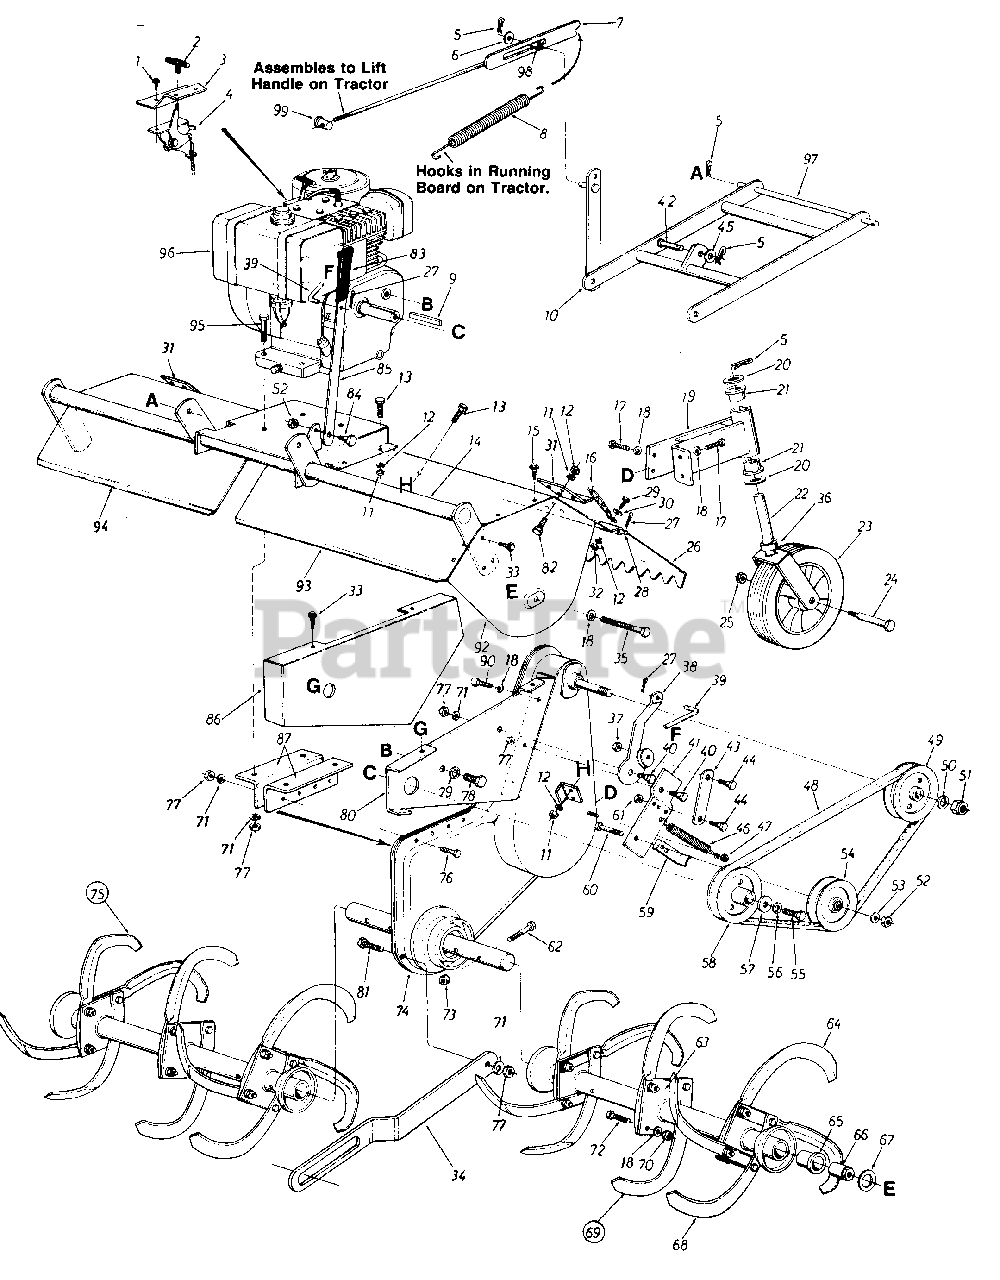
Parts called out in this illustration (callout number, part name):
1	Hex Wash. Hd. Self-Tap Scr. #8 x .50" Lg.
2	Throttle Control Knob-
3	Throttle Control Bracket
4	Throttle Control Ass'y. Comp.
5	Internal Cotter Pin
6	Fl-Wash. 1/2" I.D. x .93" O.D.
9	Sq. Key 1/4" x 1/4" x 2.00" Lg.
12	L-Wash 1/4" I. D.
13	Hex Bolt 1/4-28 x .62" Lg.
16	#2 Dog Chain x 20" Lg.
17	Hex Wash. Hd. Self-Tap Scr. 3/8-24 x .75" Lg.
18	L-Wash. 3/8" I.D.
21	Flange Bearing 3/4" I.D. x 1.00 O.D.
24	Shoulder Bolt .623" I.D. x 3.62" Lg.
25	Hex Cent. L-Nut 7/16-14 Thd.
28	L.H. Flap Rod
29	Hex Bolt 1/4-20 x .62" Lg.
30	Fl-Wash. 1/4" I.D.
33	Hex Wash. Hd. Self-Tap Scr. 1/4" x.62" Lg.
36	Spacer .752" I.D. x 1.25" O.D.
37	Hex Cent. L-Nut 5/16-18 Thd.
40	Shoulder Bolt 7/16" Dia. x 1.75" Lg.
45	Fl-Wash. .50" I.D. x 1.0" O.D. x .06
46	Extension Spring .62" O.D. x 6.12" Lg.
47	Hex Crown Nut 3/8-24 Thd.
48	"V"-Belt 1/2" x 43" Lg. [ (Kevlar)
49	1/2" "V"-Pulley 4.75" O.D. x .625" Bore
50	L-Wash. 518" I.D.
51	Hex Ins. L-Nut 5/8-18 Thd.
52	Hex Cent. L-Nut 3/8-16 Thd.
53	Fl-Wash. 3/8" I.D.
54	Idler Pulley 4.0" O.D.
55	Hex Bolt
56	L-Wash. 7/16" I.D.
57	Fl-Wash. 7/16" I.D. x 1.38"
58	1/2" "V"-Pulley .475" O.D. x 1.00" Bore
61	Hex Cent. L-Nut 5/16-18 Thd.
62	Hex Bolt 7/16-14 x 2.00" Lg.
66	Spacer
67	Thrust Wash. 1/2" I.D. x 1.55"
71	L-Wash. 5/16" I.D.
72	Hex Bolt 3/8-24 x 1.5" Lg.
73	Hex Cent. L-Nut 7/16-14 Thd.
77	Hex Nut 5/16-18 Thd.
78	Hex Bolt 1/2-20 x .88" Lg. (Grade 5)
79	L-Wash. 1/2" I.D.
80	Clutch Support Bracket
81	Shld. Bolt .435 Dia. x .265 5/16-18 Thd.
82	Hex Bolt 1/4-28 x .75" Lg.
83	Plastic Grip
84	Shoulder Bolt .498 Dia. x .212 Lg.
96	8 H.P. Engine
97	Hitch Rod
98	Push Bar Sleeve .503" I.D. x .624" O.D.
99	Ferrule
